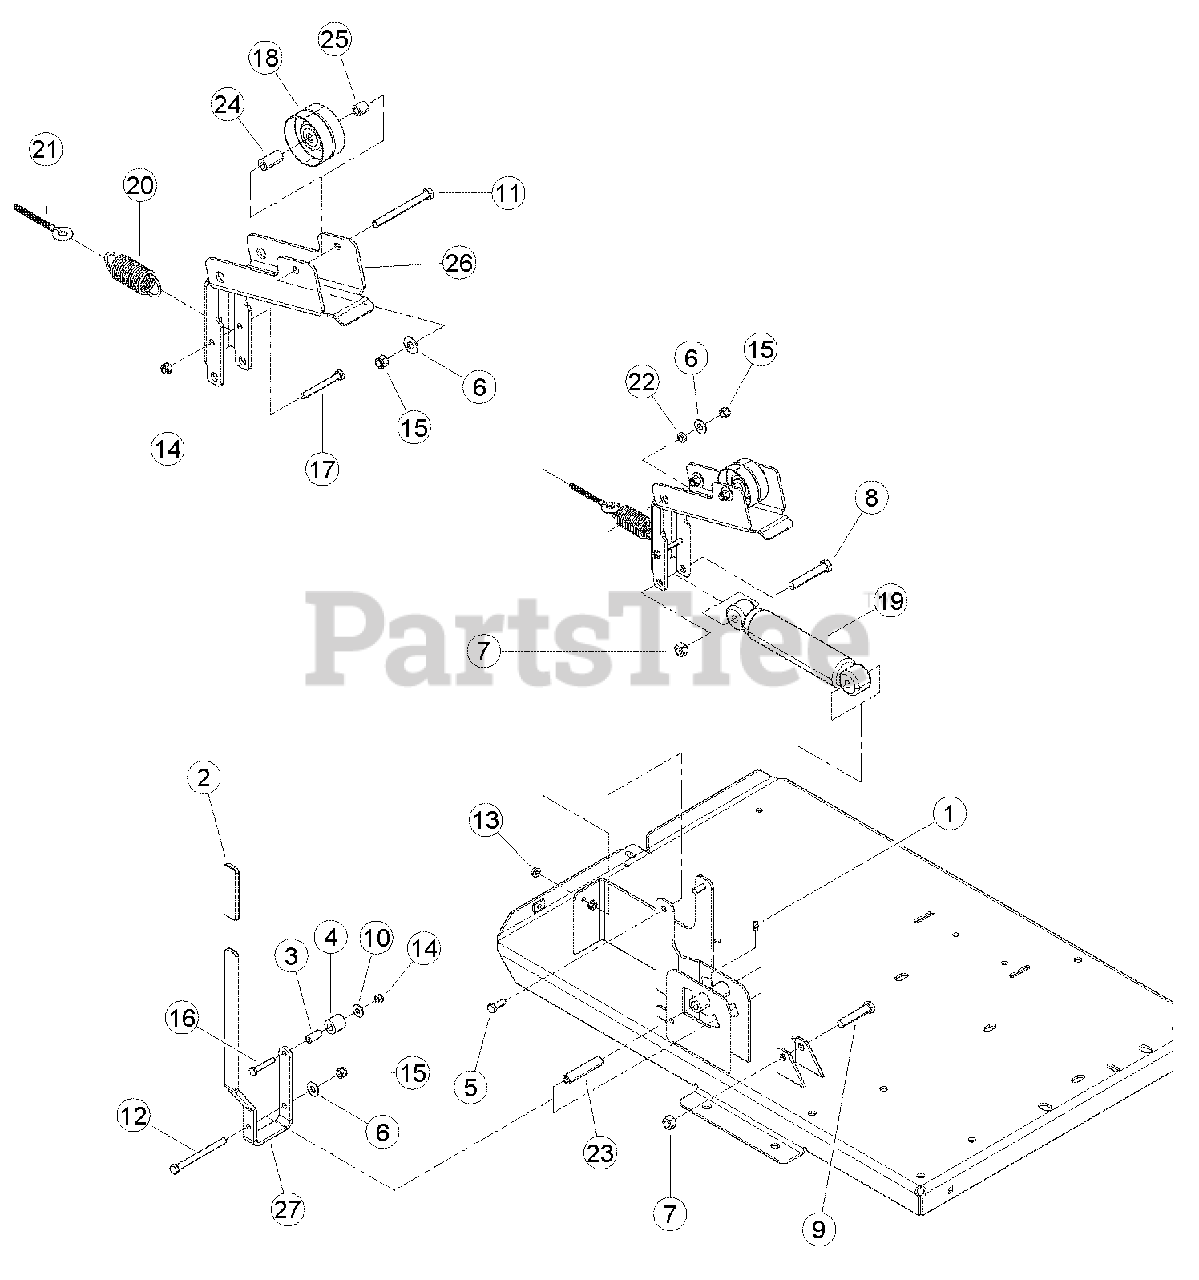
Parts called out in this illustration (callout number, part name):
1	FITTING, 1/4 SELF-TAP GREASE
2	GRIP, CLUTCH HANDLE
3	SPACER, .50 X 1.00
4	ROLLER, 0.5 X 1.00 X 1.00 NYLON
5	BOLT, 3/8 X 1 HEX HD NC GR5 ZP
6	WASHER, 3/8 FLAT
7	NUT, 1/2 CENTERLOCK GRB ZP
8	BOLT, 1/2 X 3 HEX HD
9	BOLT, 1/2 X 2-1/2 HEX HD
10	WASHER, 5/16 FLAT
11	BOLT, 3/8 X 4 HEX HD NC
12	BOLT, 3/8 X 4-1/2 HEX HD NC
13	NUT, 5/16 SERR FLANGE NC ZP
14	NUT, 5/16 NE NYLOCK
15	NUT, 3/8 NE NYLOCK
16	BOLT, 5/16 X 1-3/4 HEX HD
17	BOLT, 5/16 X 2-3/4 HCPS GR5 NC ZP
18	PULLEY, 3-1/4 FLAT IDLER
19	ABSORBER, IDLER SHOCK
20	SPRING, LOCK COMPRESSION
21	I-BOLT, 5/16 X 3-5/8
22	SPACER, IDLER PIVOT
23	BUSHING, PIVOT
24	IDLER SPACER
25	SPACER .63 X .63 PULLEY
26	BRACKET, IDLER
27	LEVER, CHIPPER ENGAGEMENT
